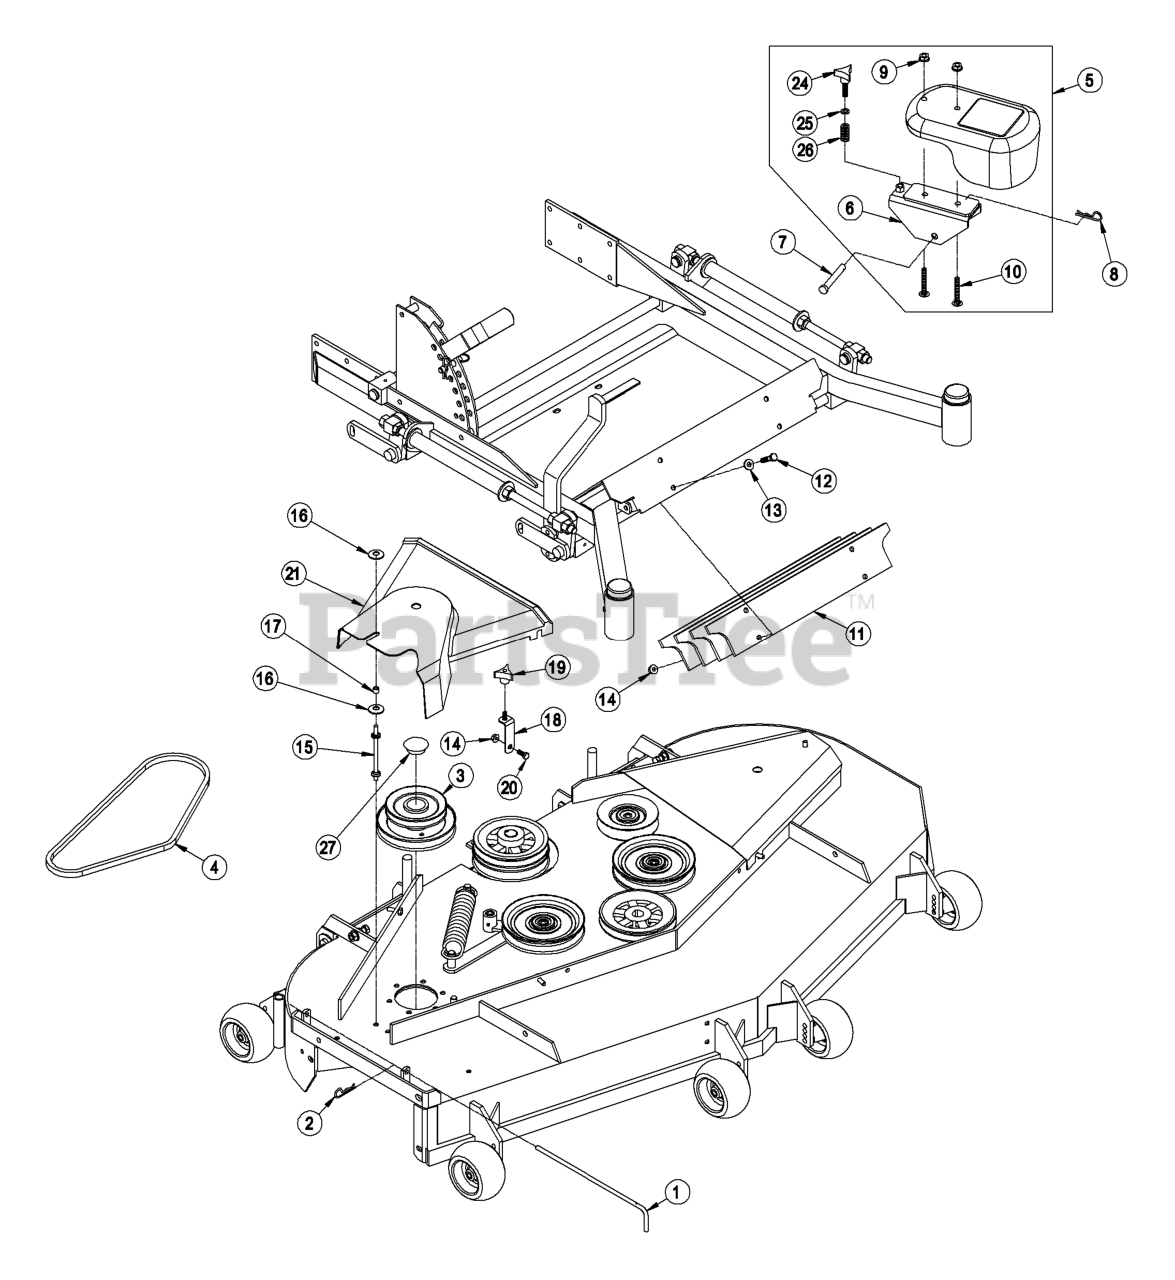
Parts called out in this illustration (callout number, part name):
1	PIN, CHUTE PIVOT
2	PIN-COTTER
3	JACKSHAFT, LZUV72
4	BELT, BLOWER DRIVE 72
5	ASM, WEIGHT 2.0" 43 POUND
6	WLD, BRACKET 2.0 ARM
7	PIN-CLEVIS
8	PIN-COTTER
9	NUT-HHF, WHIZ
10	BOLT-SQH
12	SCREW-HH
13	WASHER-PLAIN
15	STUD,BELT SHIELD 4 INCH
17	Spacer, Grommet
18	Support, Belt Cover
19	Knob
21	COVER, BELT 72
25	WASHER-FLAT
27	PLUG, BLACK NYLON 1.75
